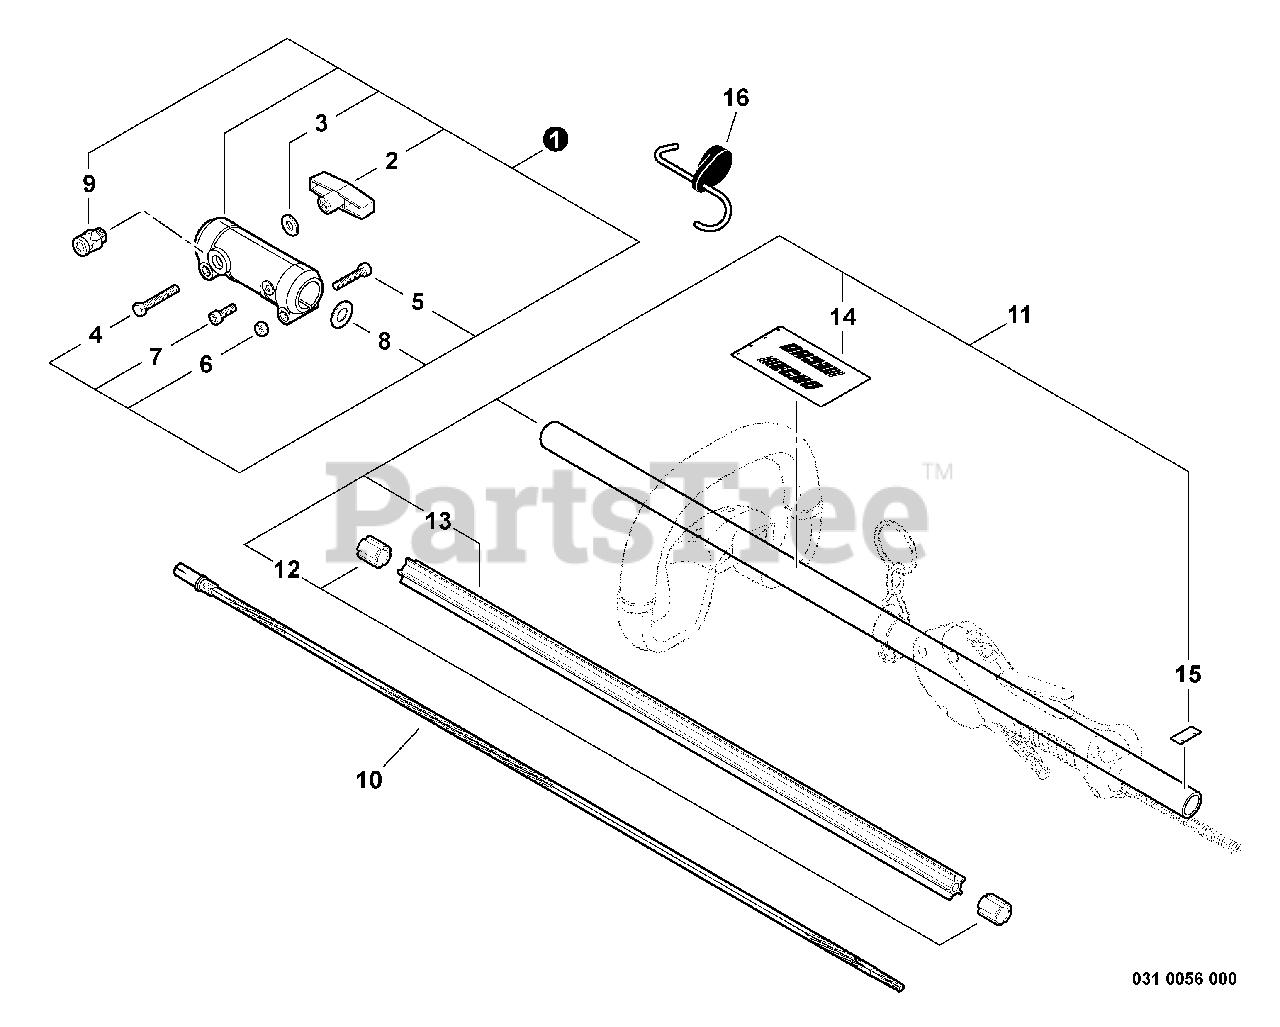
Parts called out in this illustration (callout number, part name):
1	COUPLER ASSY
2	KNOB, FASTENER
3	WASHER 6.6×20×1.6
4	BOLT 6×40
5	BOLT 6×25
7	BOLT M6×10
8	WASHER 18 SPR STEEL
9	LATCH ASSY
10	DRIVESHAFT - FLEXIBLE
11	MAIN PIPE ASSY
13	LINER - FLEXIBLE
14	LABEL, HANDLE LOCATION
15	LABEL - ALIGNMENT
16	HANGER, ATTACHMENT
